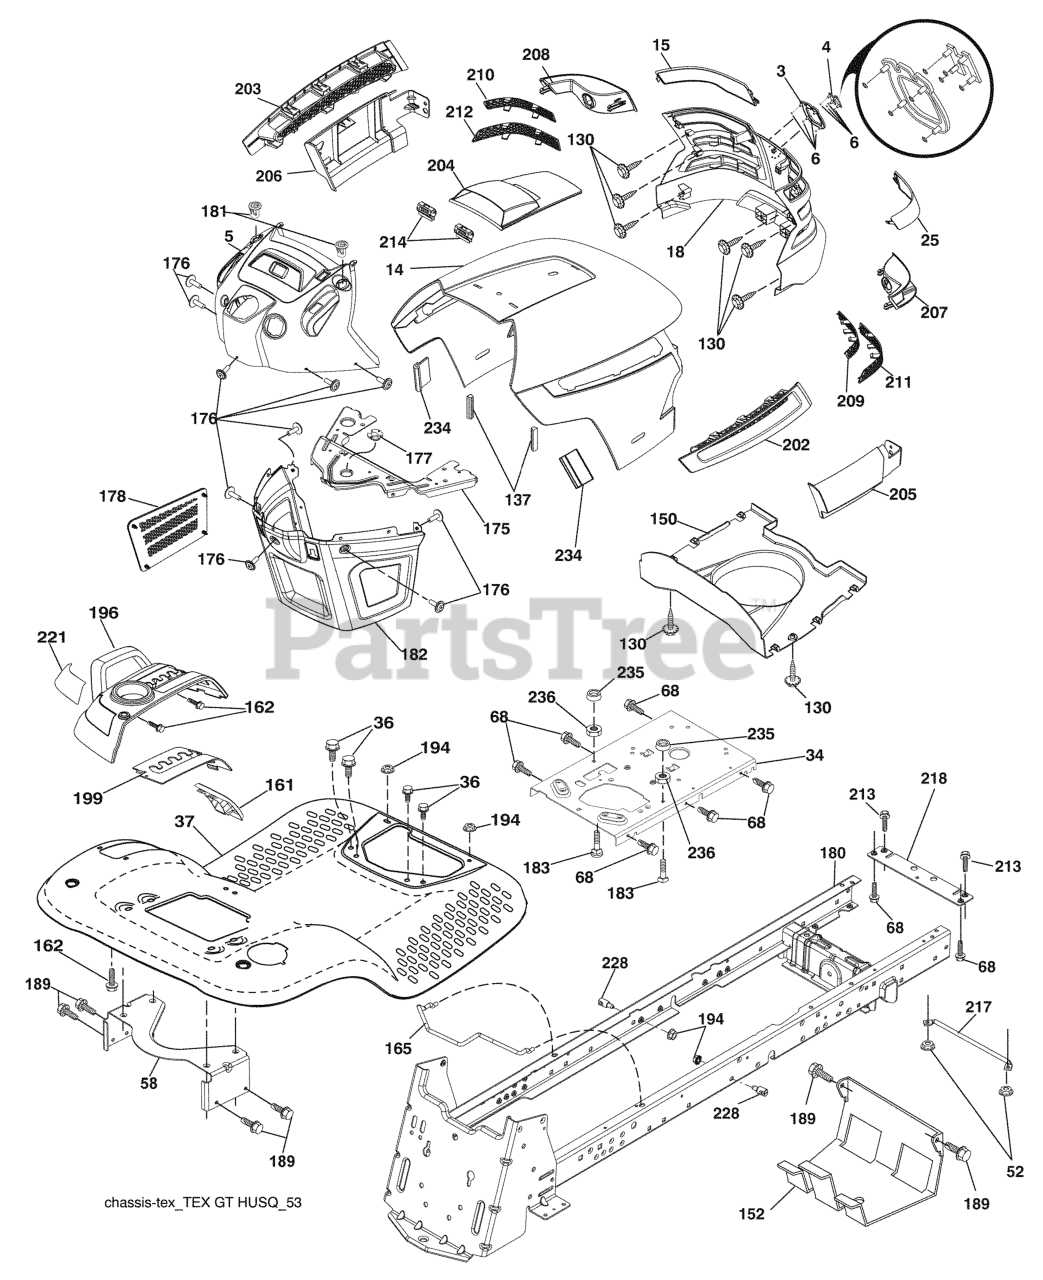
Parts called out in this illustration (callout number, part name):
3	TRIM.HUSQ.TG/CRD.SERVICE
4	RP LOGO
5	DASH.ASM.GTHUSQTX.RGS.ELECT.CK
6	NUT PUSH M
14	HOOD
15	LENS.LH.TEX.GT.HUSQ.CL
18	GRILL.ASM.HUSQ.TG/CRD.W/TRIM
25	LENS.RH.TEX.GT.HUSQ.CL
34	PLATE.ENGINE.WELDED.CHASSIS
36	SCREW 5/16"
37	FENDER.PNT.TX.GT.CH/FW.ORANGE
52	LOCKNUT
58	BRKT.SUPPORT.FNDR/TANK
68	Screw Thdrol 5/16-18 x 1/2
130	SCREW.#10 X 0.750.BOS
137	BUMPER DASH
150	AIR.DUCT.HOOD.TEX.GT.HUSQ
152	SHIELD.BROWNING.W/TEX
161	CONSOLE.FUEL.WINDOW.HU
162	SCREW.HI-LO.CONSOLE
165	SUPPORT.TANK.REAR.W/TEX
175	PLATE.CROSSMEMBER.HUSQ
176	SCREW.#10-24X5/8.RN.QU
177	BUSHING, STEERING
178	CARGO.ASM.NET.TXGT.W/C
180	CHASSIS.GT.SLOPED.DRAWBAR.
181	BUSHING.MNT.FEND.CRGO.
182	DASH.LOWER.COMMON.12V.ADAPTOR
183	BOLT.5/16-18X1-1/4 FULL.THREAD
189	SCREW
194	NUT LOCK HEX FLANGE 5/16-18
196	CONSOLE.ASM.DCKLFT.W/RF.HQ.DLR
199	PLATE.DECK.LIFT.HUSQVARNA.GT
202	VENT.SIDE.HOOD.HUSQ.RH.GREY
203	VENT.SIDE.HOOD.HUSQ.LH.GRAY
204	HOOD VENT
205	SKIRT.HOOD.SIDE.HUSQ.RH.GREY
206	SKIRT.HOOD.SIDE.HUSQ.LH.GREY
207	BEZEL.RH.TEX.GT.HUSQ
208	BEZEL.LH.TEX.GT.HUSQ
209	INSERT.HEX.GRILL.HUSQ.GREY
210	INSERT.HEX.GRILL.HUSQ.
211	INSERT.HEX.GRILL.HUSQ.
212	INSERT.HEX.GRILL.HUSQ.
213	BOLT
214	CLIP.RETAINER.TINNER.
217	ROD.PIVOT.HOOD
218	X-PIECE.HOOD.STOP.NON/
221	REFLECTOR.LH.TEX GT HU
228	STUD.FASTNER.W/ANTI-ROTATE
233	BOLT.SHOULDER
234	BUMPER.HOOD.TEX.HUSQVARNA
235	SPACER FENDER
236	NUT.CENTERLOCK.5/16-
